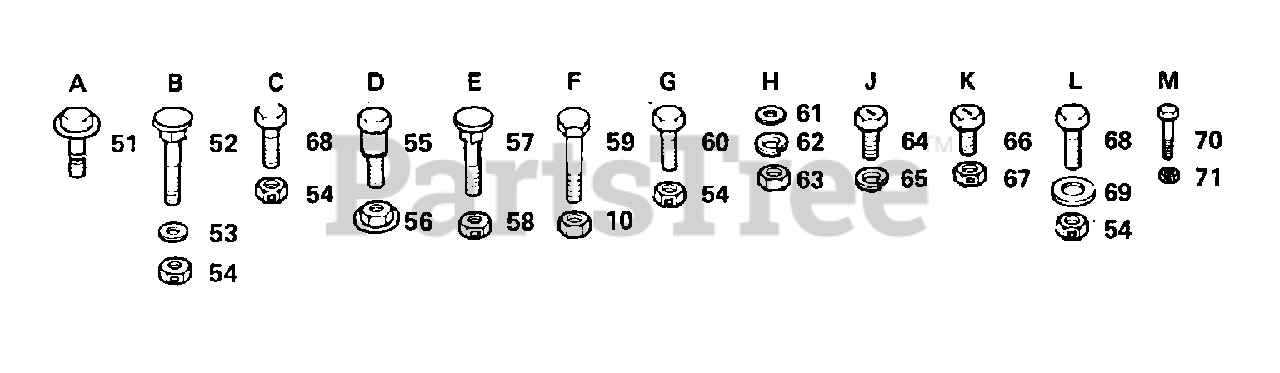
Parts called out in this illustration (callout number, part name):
51	SCREW LT
52	BOLT
53	WASHER
55	SHOULDER BOLT T
56	NUT T
57	BOLT
58	LOCKNUT
59	BOLT
61	WASHER PM
68	BOLT
69	WASHER M
70	BOLT
